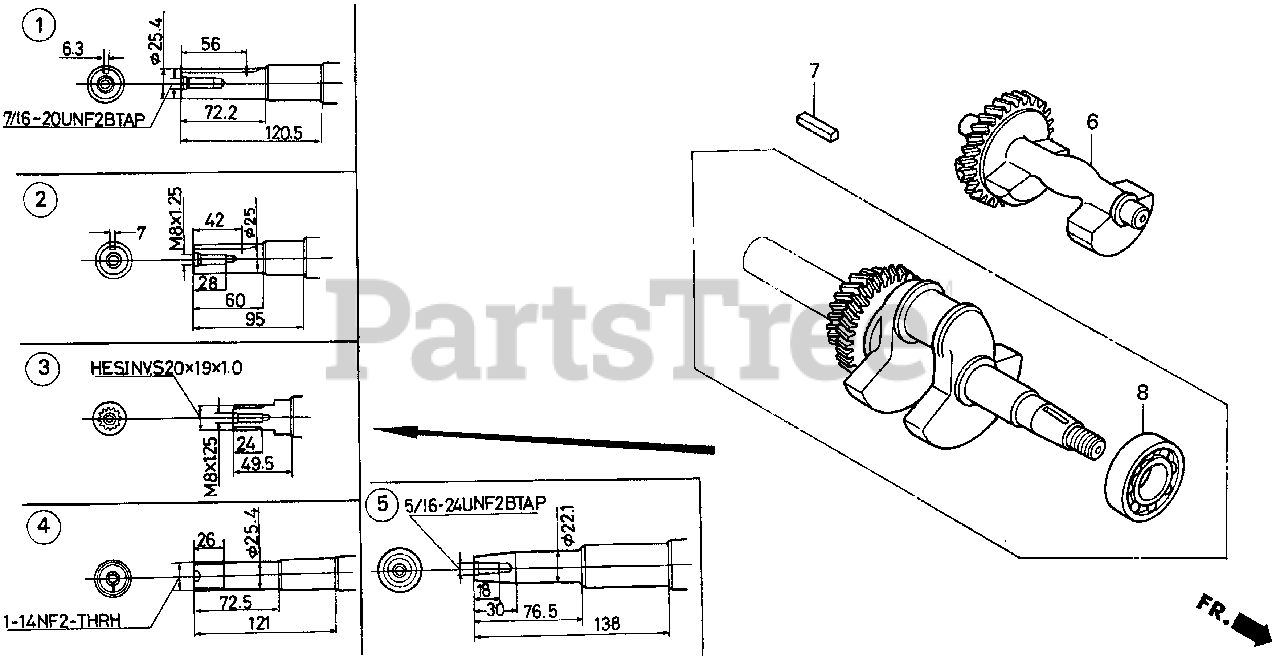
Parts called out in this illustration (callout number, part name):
2	CRANKSHAFT (S-TYPE)(BALANCER)
6	WEIGHT, BALANCER
8	BEARING, RADIAL BALL (6206 SH)
